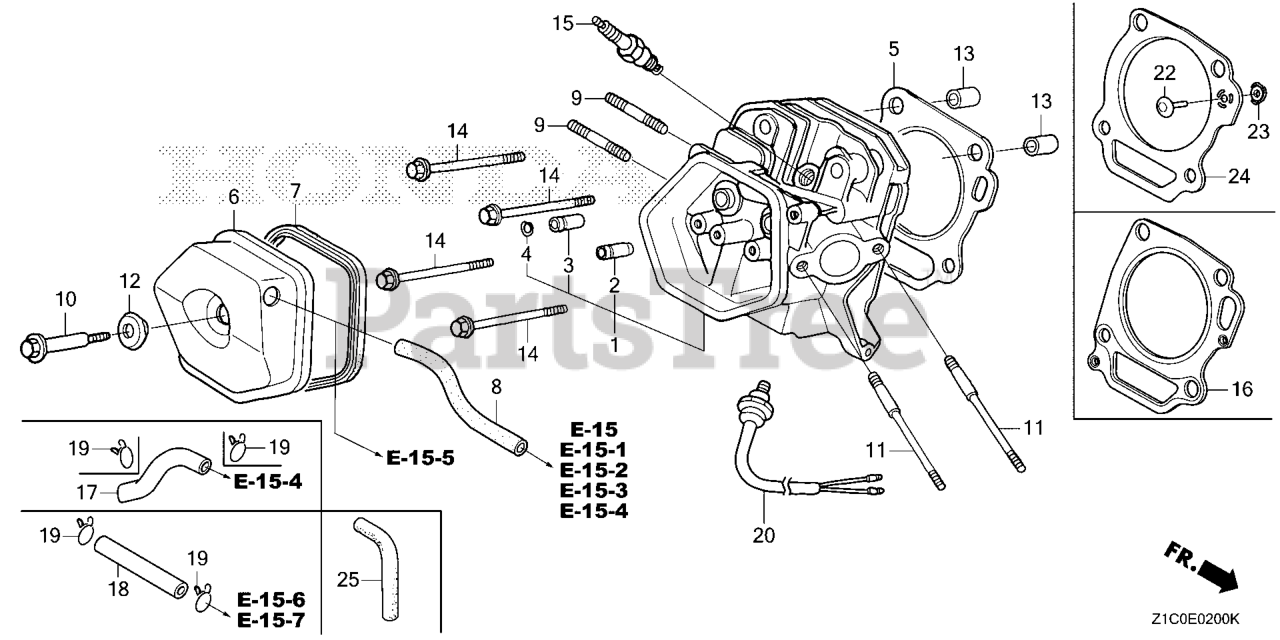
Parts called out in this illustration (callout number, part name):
1	CYLINDER HEAD
4	CLIP, VALVE GUIDE
5	GASKET, CYLINDER HEAD (NIPPON LEAKLESS)
6	COVER, HEAD (BREATHER TUBE JOINT)
7	GASKET, CYLINDER HEAD COVER
9	BOLT 2, STUD (8X32)
10	BOLT, HEAD COVER
11	BOLT, STUD (8X131.5)
12	WASHER, HEAD COVER
13	PIN A, DOWEL (12X20)
14	BOLT, FLANGE (10X80)
15	SPARK PLUG (BPR5ES) (NGK)
15	SPARK PLUG (BPR6ES) (NGK)
15	SPARK PLUG (W16EPR-U) (DENSO)
18	TUBE, BREATHER
19	CLIP, BREATHER TUBE
